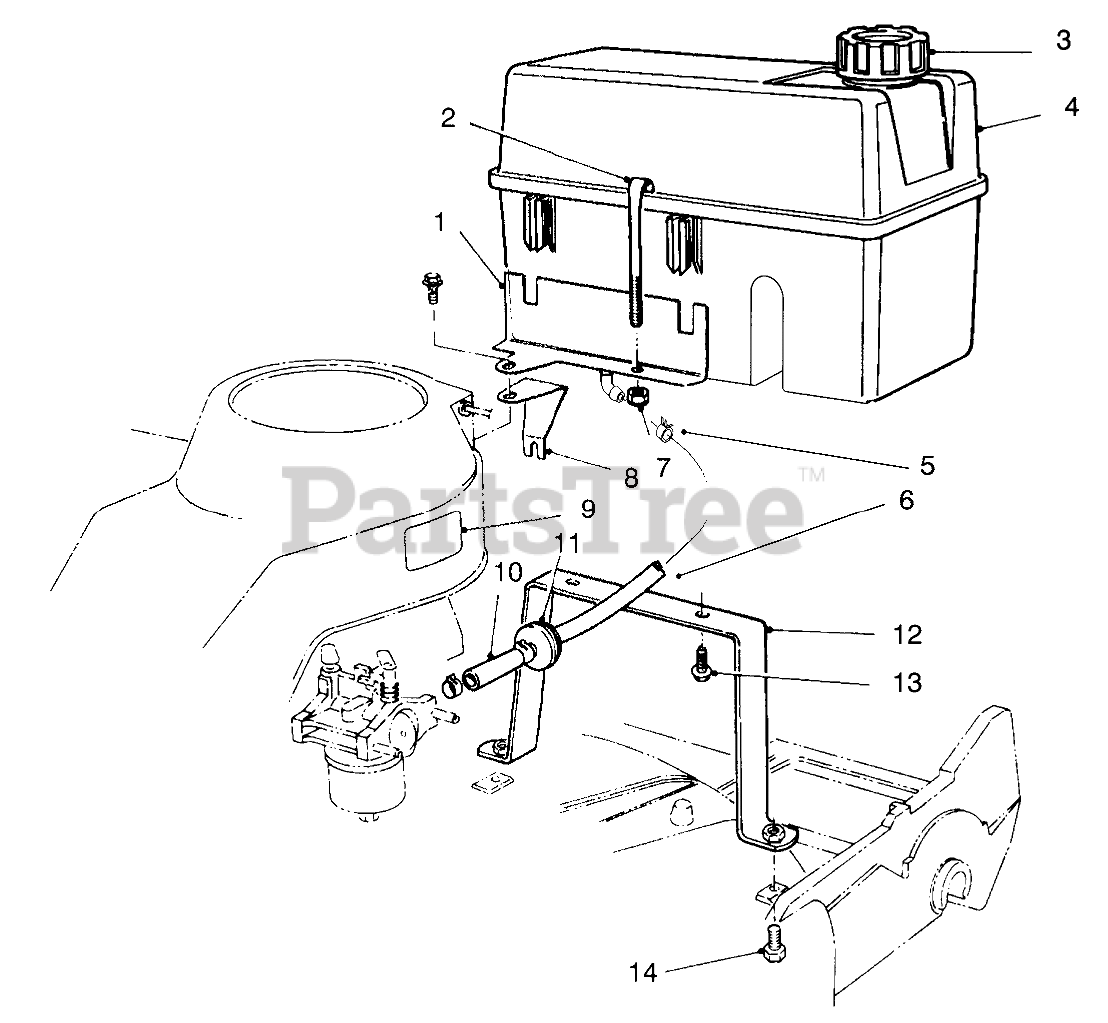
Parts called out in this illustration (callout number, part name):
1	Bracket Tank
2	RETAINER - FUEL TANK
3	GAS CAP ASM
4	Tank-Gas
5	CLAMP-FUEL LINE
6	HOSE-FUEL
7	NUT-LOCK, NI
8	Support-Bracket
9	DECAL - FUEL
10	LINE-GAS
11	FILTER-FUEL
12	Base-Tank
13	SCREW-HWH
14	SCREW-HH
